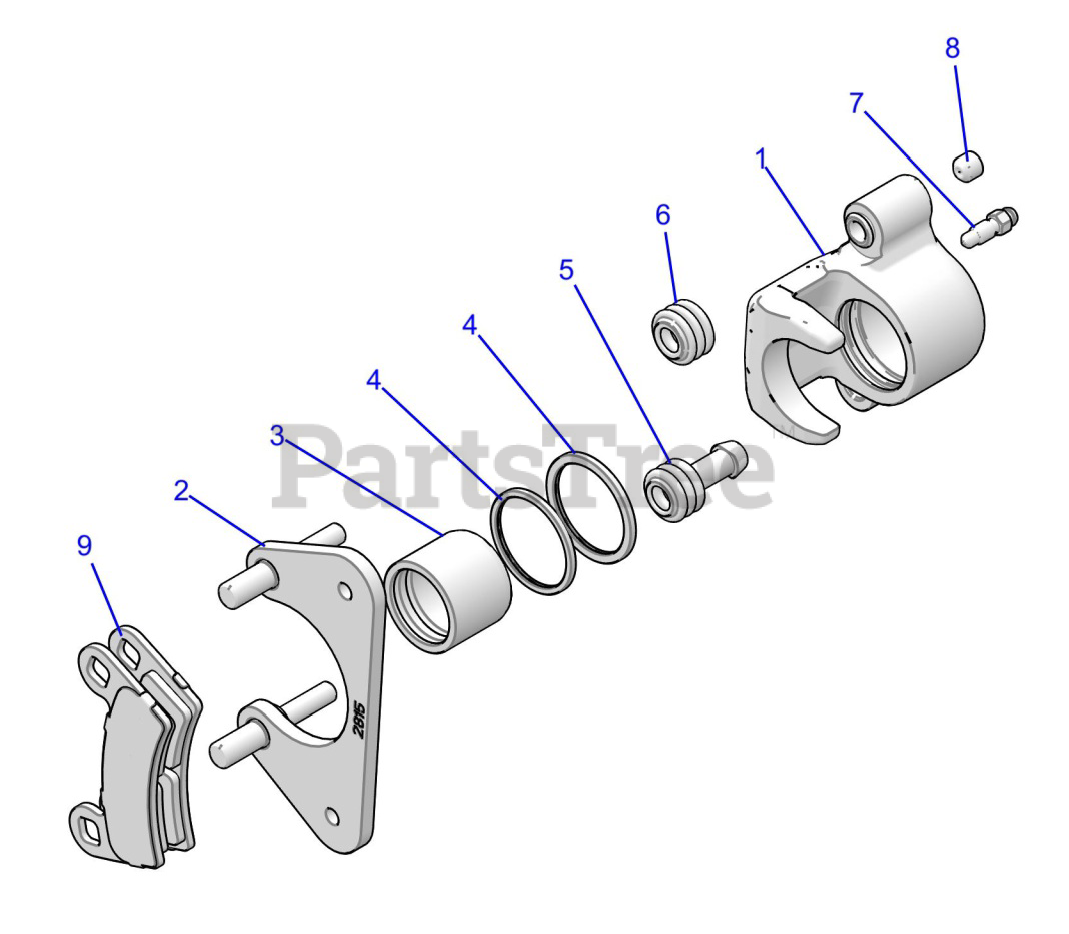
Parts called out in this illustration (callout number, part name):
2	ASM-CALIPER MNT,SGL BORE
3	PISTON-BRAKE,1.5,AL,GROOVED
4	SEAL-CALIPER INNER,1.50"
5	BOOT-PIN BUSHING
6	BOOT-PIN SEAL
7	SCR-M7X1.0,BLEEDER,OLIVE D
8	SCR-M10X1.0X8,SOC SET-OD
9	KIT, BRAKE PAD
